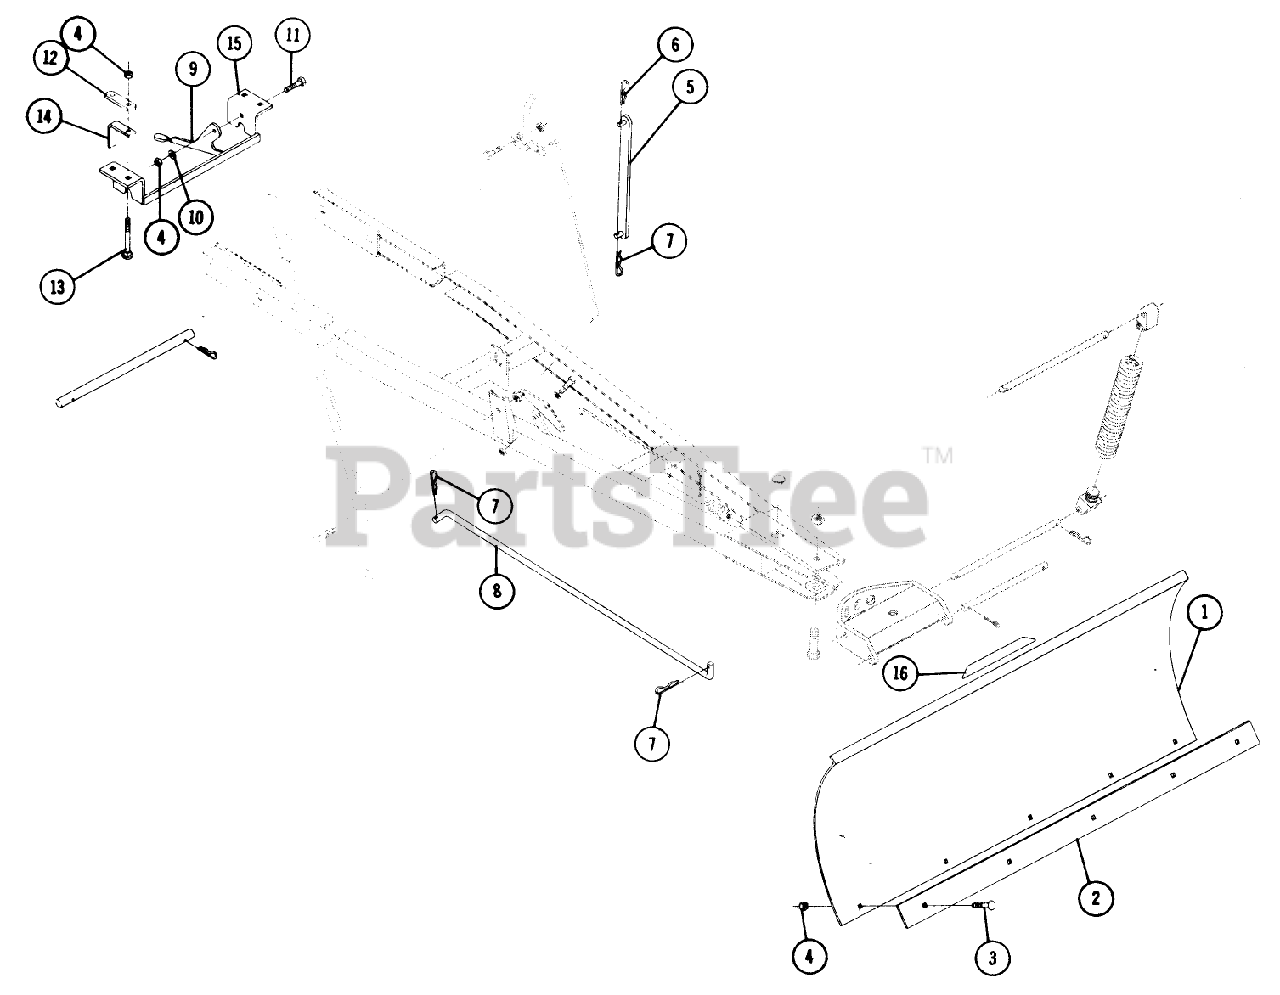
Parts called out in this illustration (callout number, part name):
1	Blade
2	Plate
3	Bolt-3/8-16 x 3/4
4	3/8-16 E.S.
5	LIFT BAR ASSY R
6	Hairpin
7	Hairpin
8	Rod Blade Control
9	Latch Hitch
10	Washer
11	Bolt 3/8-16 x 1
12	Link
13	Bolt-Carr. 3/8-16 x 3 1/2
14	SPACER-BRACKET
15	Hitch Axle Mounting
16	Decal
